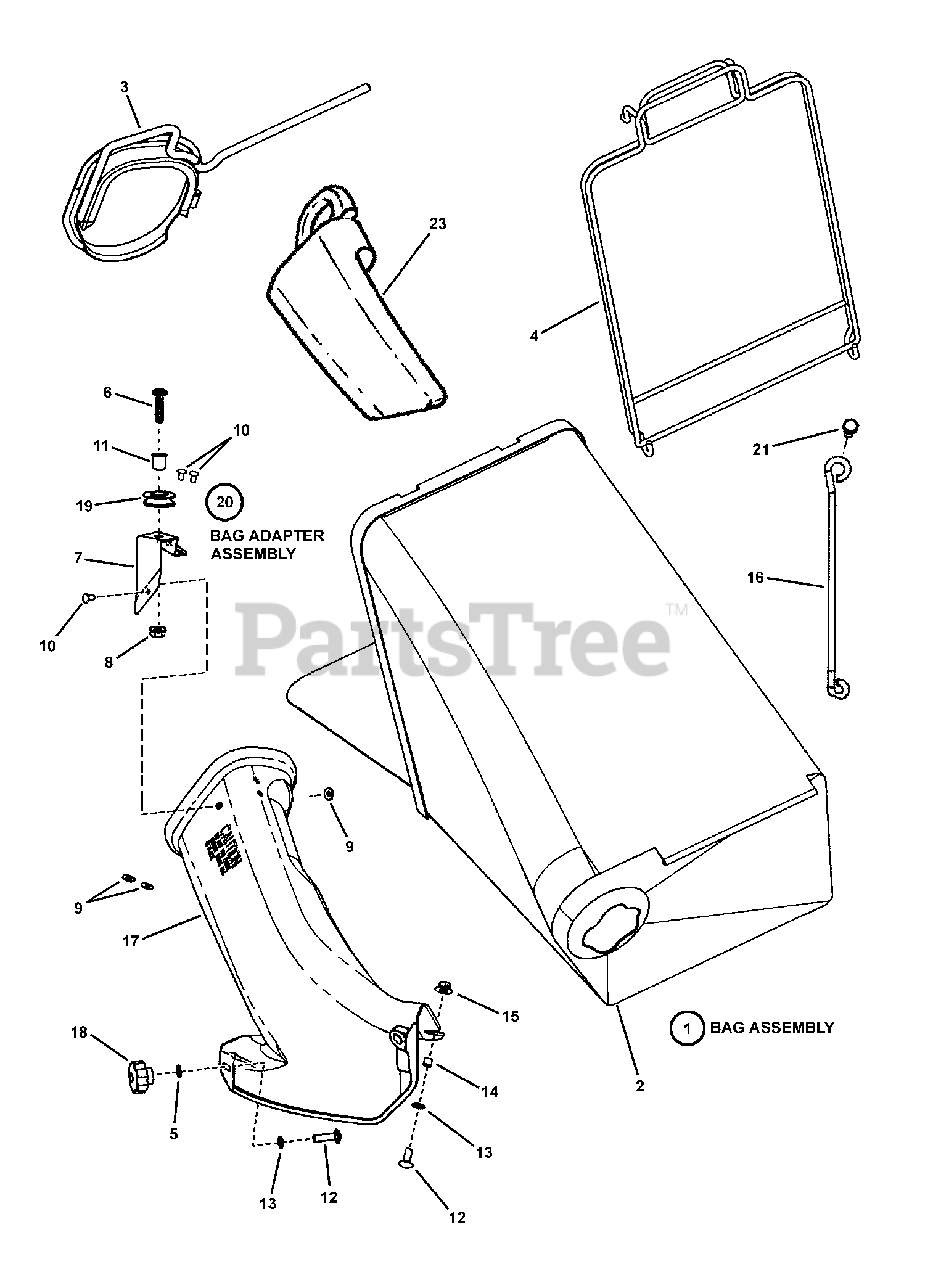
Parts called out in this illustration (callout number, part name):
1	BAG ASSEMBLY, (Door)
2	GRASS BAG, (Door w/Gray Letters)
3	CONNECTOR, Grass Bag (weldment)
4	ASSEMBLY, Bag Wire (12" Wide)
5	WASHER, 5/16" Internal/External Tooth Lock
6	SCREW, 5/16-18 x 1-1/4" Pan Head Machine
7	BRACKET, Rope Guide
8	NUT, 5/16-18 Hex Flange Lock, GR 5
9	WASHER, 15/32" Flat
10	RIVET, 3/16 x .344
11	BUSHING, Flange, .381 x .625 x .62
12	BOLT, 5/16-18 x 3/4" Short Neck Carriage GR 5
13	RETAINER, 5/16" Bolt
14	SPACER, .316 I.D. x .375 O.D. x .310 thick
15	NUT, 5/16-18 Hex Large Flange Center Lock
16	BRACE, Bag Adapter
17	ADAPTER, Grass Bag
18	KNOB, Fluted, 5/16-18 x .633
19	PULLEY, Nylon
20	ASSY, Grass Bag Adapter
21	SCREW, M6 x 1.0 x 30MM Hex Head Cap
23	PLUG, Chute Adapter
